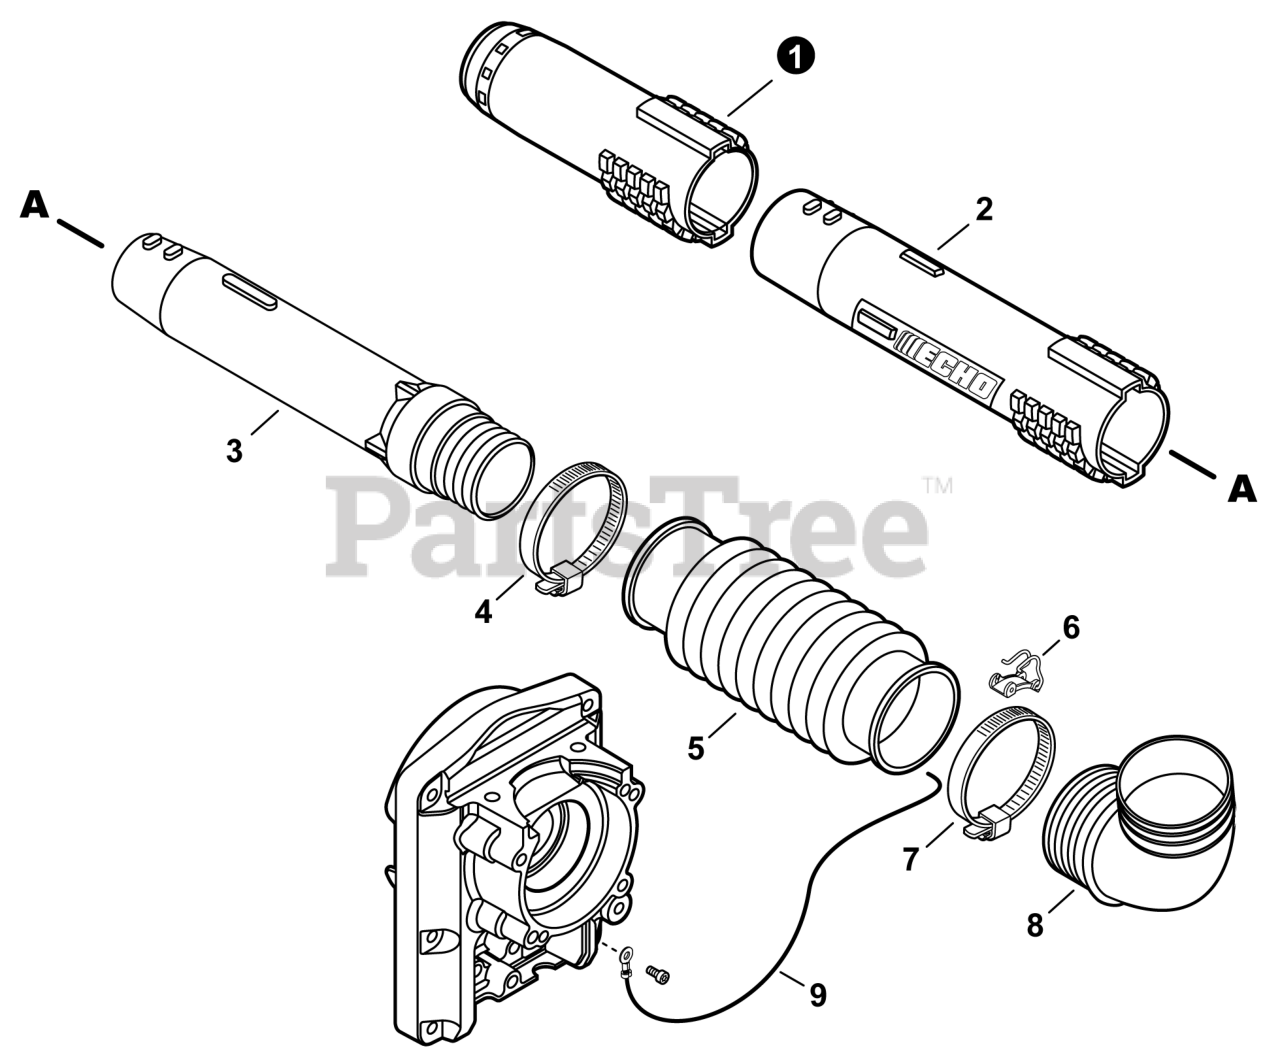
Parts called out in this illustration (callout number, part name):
1	TUBE, BLOWER - NOZZLE
2	TUBE, BLOWER - STRAIGHT
3	TUBE, BLOWER - SWIVEL
4	CLAMP - BAND 58.7 MM / 82.5 MM
5	TUBE, BLOWER - FLEXIBLE
6	CLIP, CABLE
7	CLAMP - BAND 78 MM / 103 MM
8	TUBE, BLOWER - ELBOW
9	WIRE, STATIC DISCHARGE
